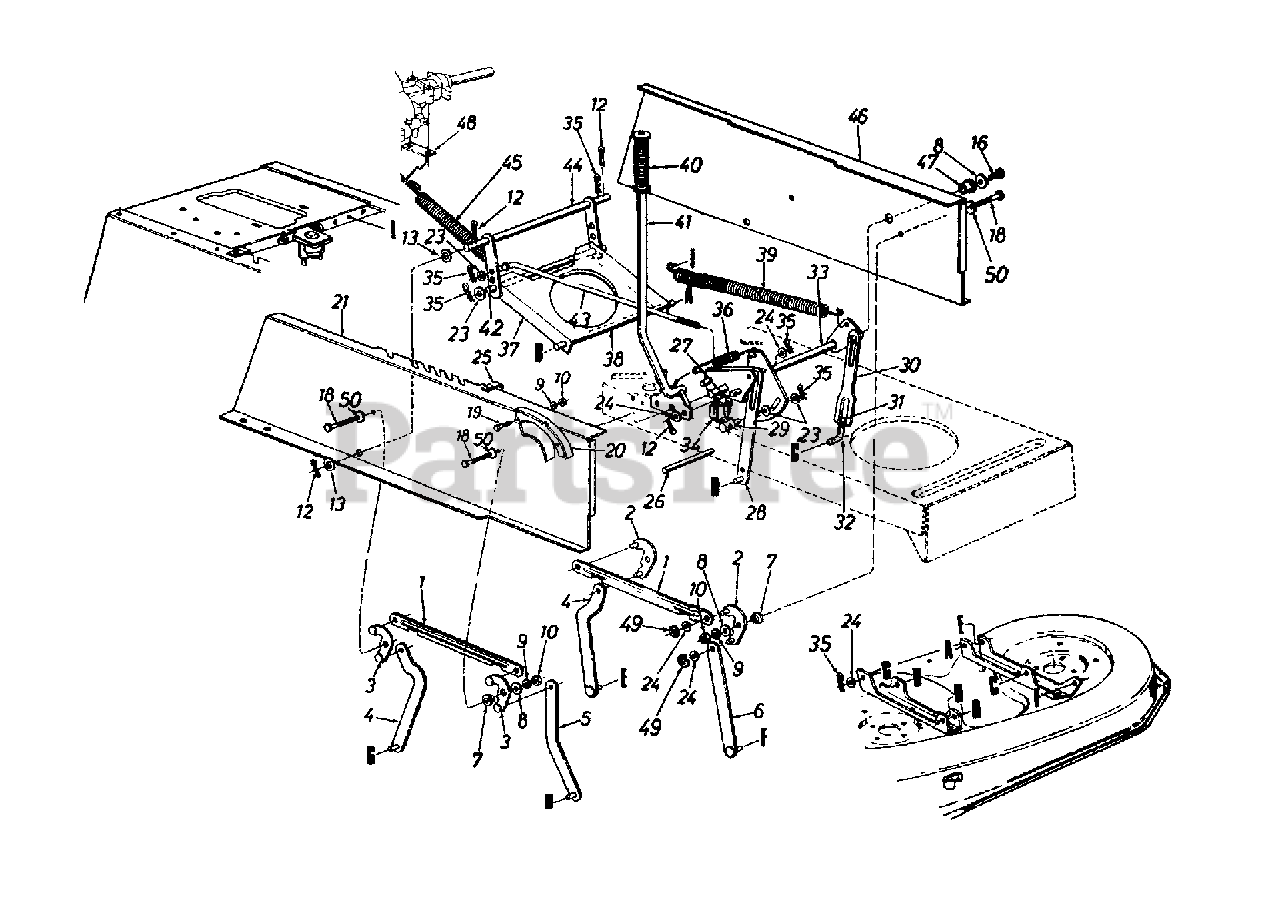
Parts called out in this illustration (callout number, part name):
3	Pivot Link Ass'y.-R.H.
7	Shld. Spacer .318" I.D.
8	Fl-Wash. .344" I.D. x .62" O.D.
9	L-Wash. 5/16" I.D.
10	Hex Nut 5/16-18 Thd. (Gr. 5)
12	Cotter Pin 1/8" Dia.
13	Fl-Wash. .635" I.D. x 1.0" O.D.
16	Hex Wash. TT-Tap Scr. 5/16-18 x .75"
18	Hex Wash. Hd. Scr. 5/16-18 x .875"
19	Hex Bolt 5/16-18 x .75" Lg.
24	Fl-Wash. .531" I.D. x .93" O.D.
26	Running Board Rod
27	Hex Wash. Hd. Tap Scr.
31	Hex Nut 1/2-20 Thd. (Gr. 5)
32	Lift Link Adjuster
33	Lift Shaft Ass'y.
34	Safety Switch (Deck)
35	Inter. Cotter Pin 3/8" Dia.
36	Extension Spring
39	Extension Spring
40	Grip (Lift Handle)
43	Disengagement Rod
49	"E"-Ring
50	Bell-Wash. .325" I.D.
